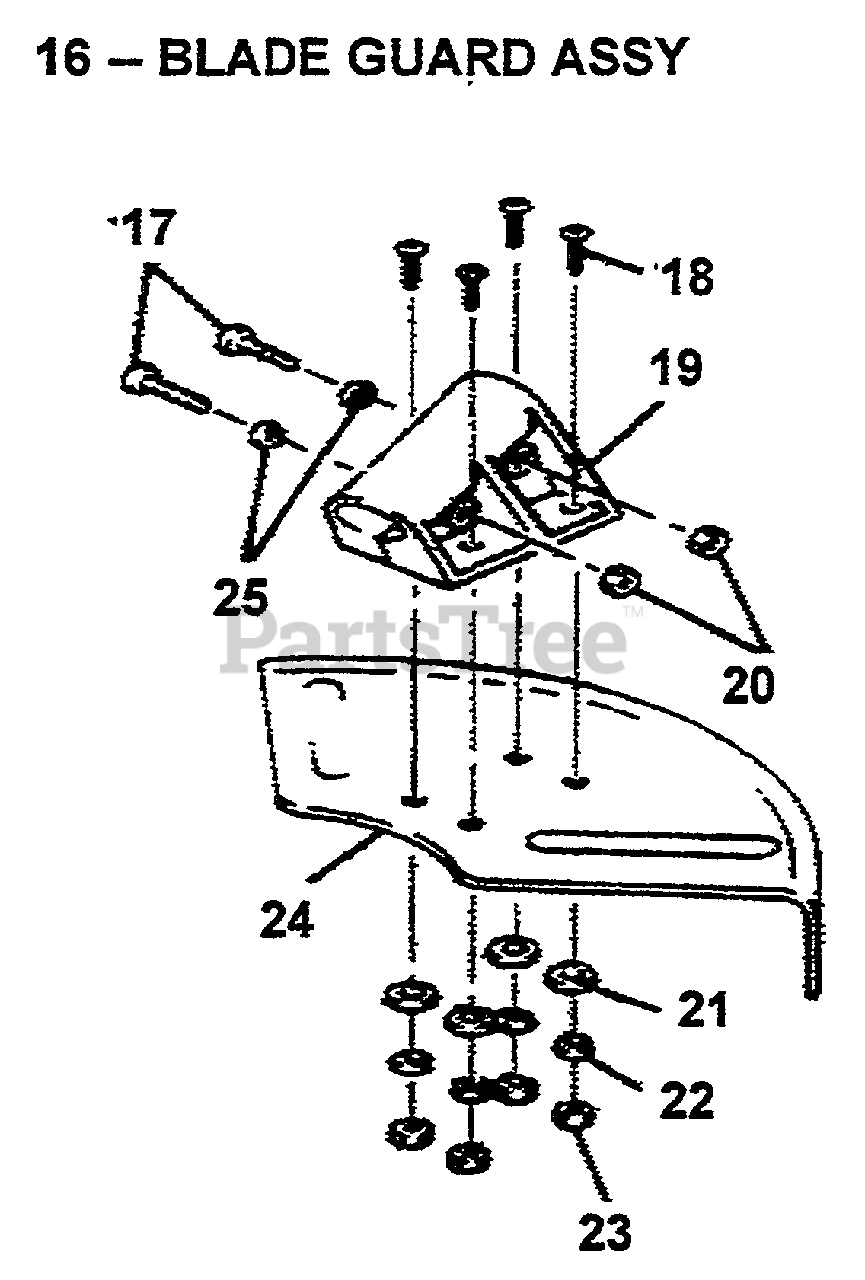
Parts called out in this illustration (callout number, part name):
16	BLADE GUARD ASSY
19	BLADE GUARD BRACKET
23	NUT
24	GUARD
